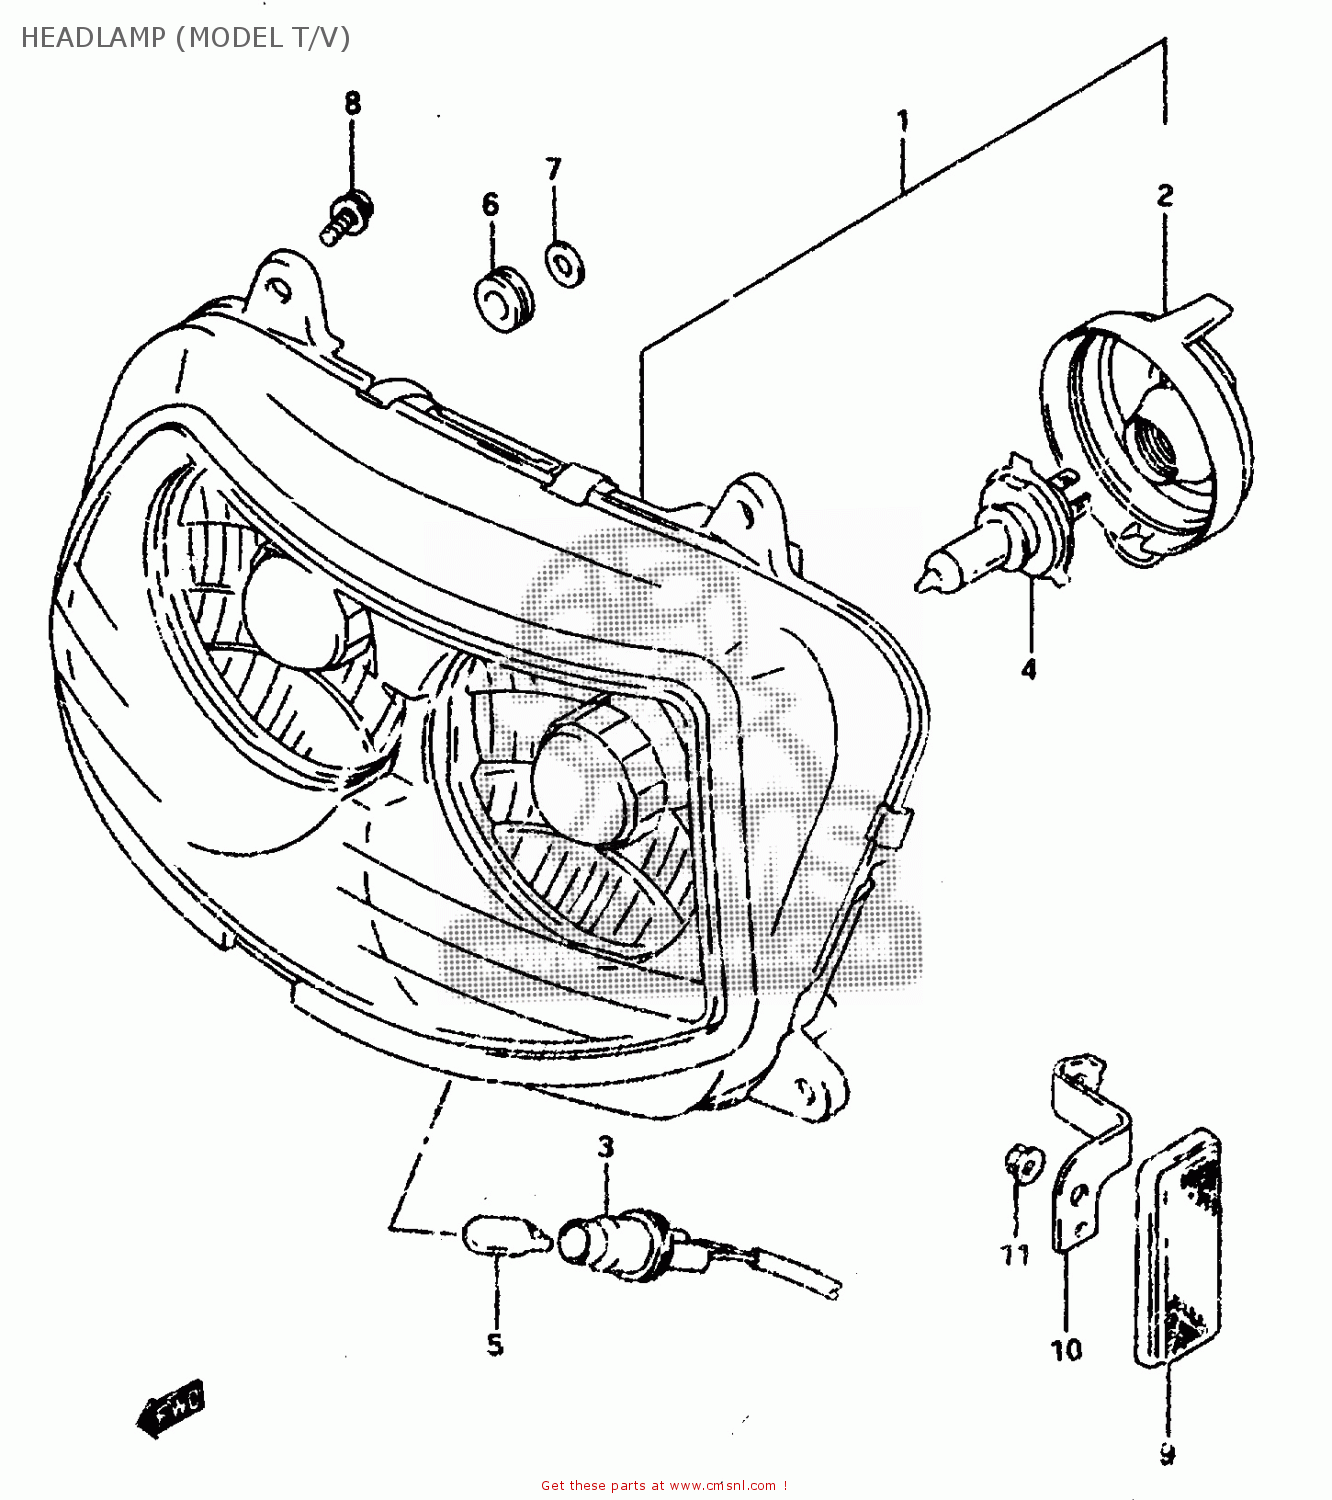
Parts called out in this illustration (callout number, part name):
1	HEADLAMP ASSY
2	COVER,SOCKET
3	SOCKET ASSY
4	BULB(12V60/55W,H4)
5	BULB(12V3.4W,STANLEY,A72A)
6	WASHER(5.5X16X1.2)
7	CUSHION
8	GROMMET
9	WASHER
10	NUT
11	SCREW
12	LAMP ASSEMBLY,FRONT POSITION
13	BULB(12V5W)
14	SOCKET ASSY
15	CUSHION
16	WASHER (4X16X1.2)
17	SCREW
18	REFLECTOR,REFLEX FR
19	BRACKET,FR SIDE RR,R
20	NUT
